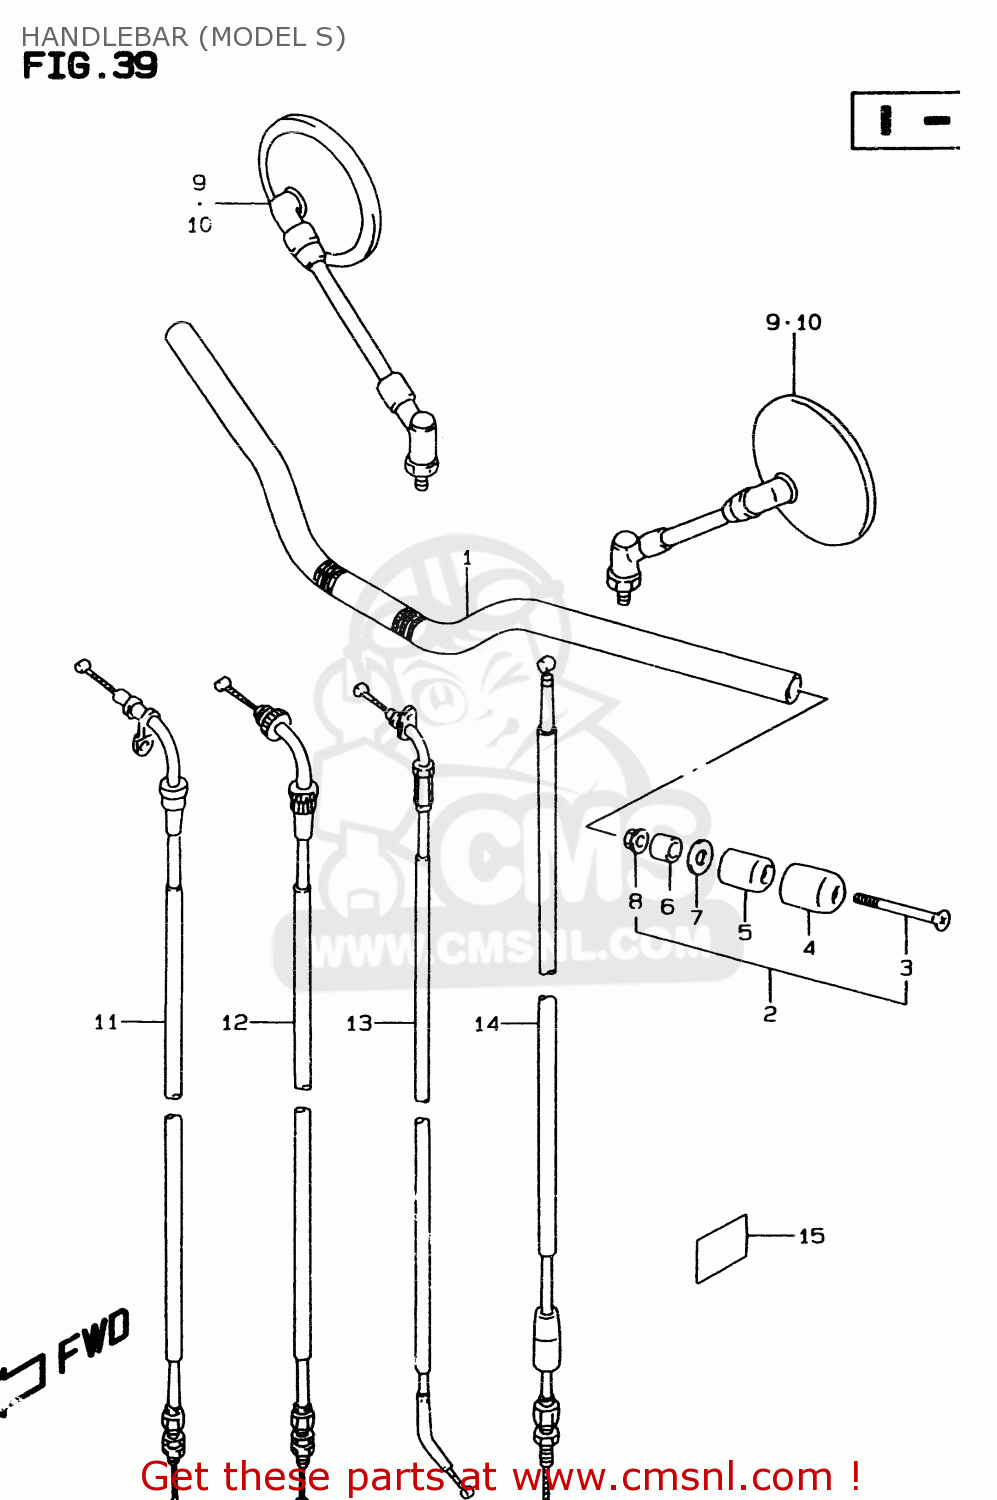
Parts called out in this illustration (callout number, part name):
1	HANDLEBAR
2	BALANCER SET,HANDLEBAR
3	SCREW
4	CAP,BALANCER
5	BALANCER,HANDLE
6	SPACER,BALANCER
7	EXPANDER,HANDLE BALANCER
8	NUT
9	MIRROR ASSY,RH
10	MIRROR ASSY,RH
11	CABLE ASSY,THROTTLE NO.1
12	CABLE ASSY,THROTTLE NO.2
13	CABLE COMP,STARTER
14	CABLE ASSY,CLUTCH
15	PROTECTOR,FRAME COVER FR
